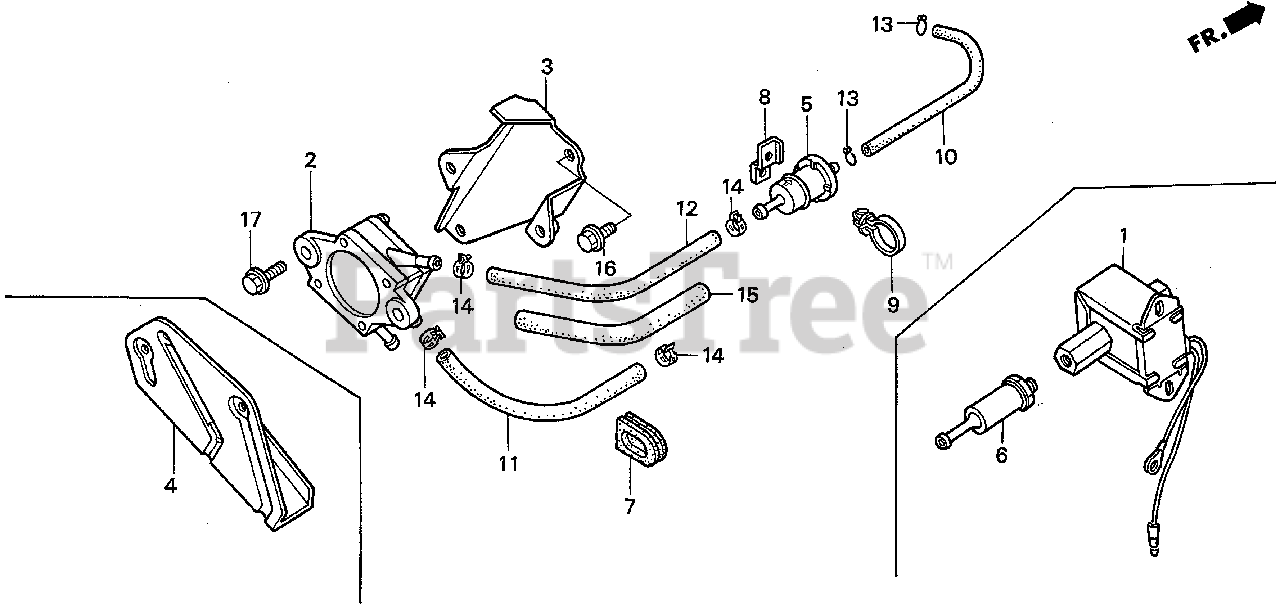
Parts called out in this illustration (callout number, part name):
2	PUMP ASSY., FUEL
3	STAY, FUEL PUMP
5	FILTER, FUEL
7	GROMMET, WIRE
8	BASE, CLIP
9	CLIP, WIRE HARNESS
10	BULK HOSE, FUEL (4.5X3000) (4.5X110)
11	BULK HOSE, FUEL (5.5X8000) (5.5X195)
12	BULK HOSE, FUEL (5.5X8000) (5.5X215)
13	CLIP, TUBE (B8)
14	CLIP, TUBE (10.5MM)
15	BULK HOSE, VINYL (11X13X3000) (11X13X160)
16	BOLT, FLANGE (6X8)
17	BOLT, FLANGE (6X14)
